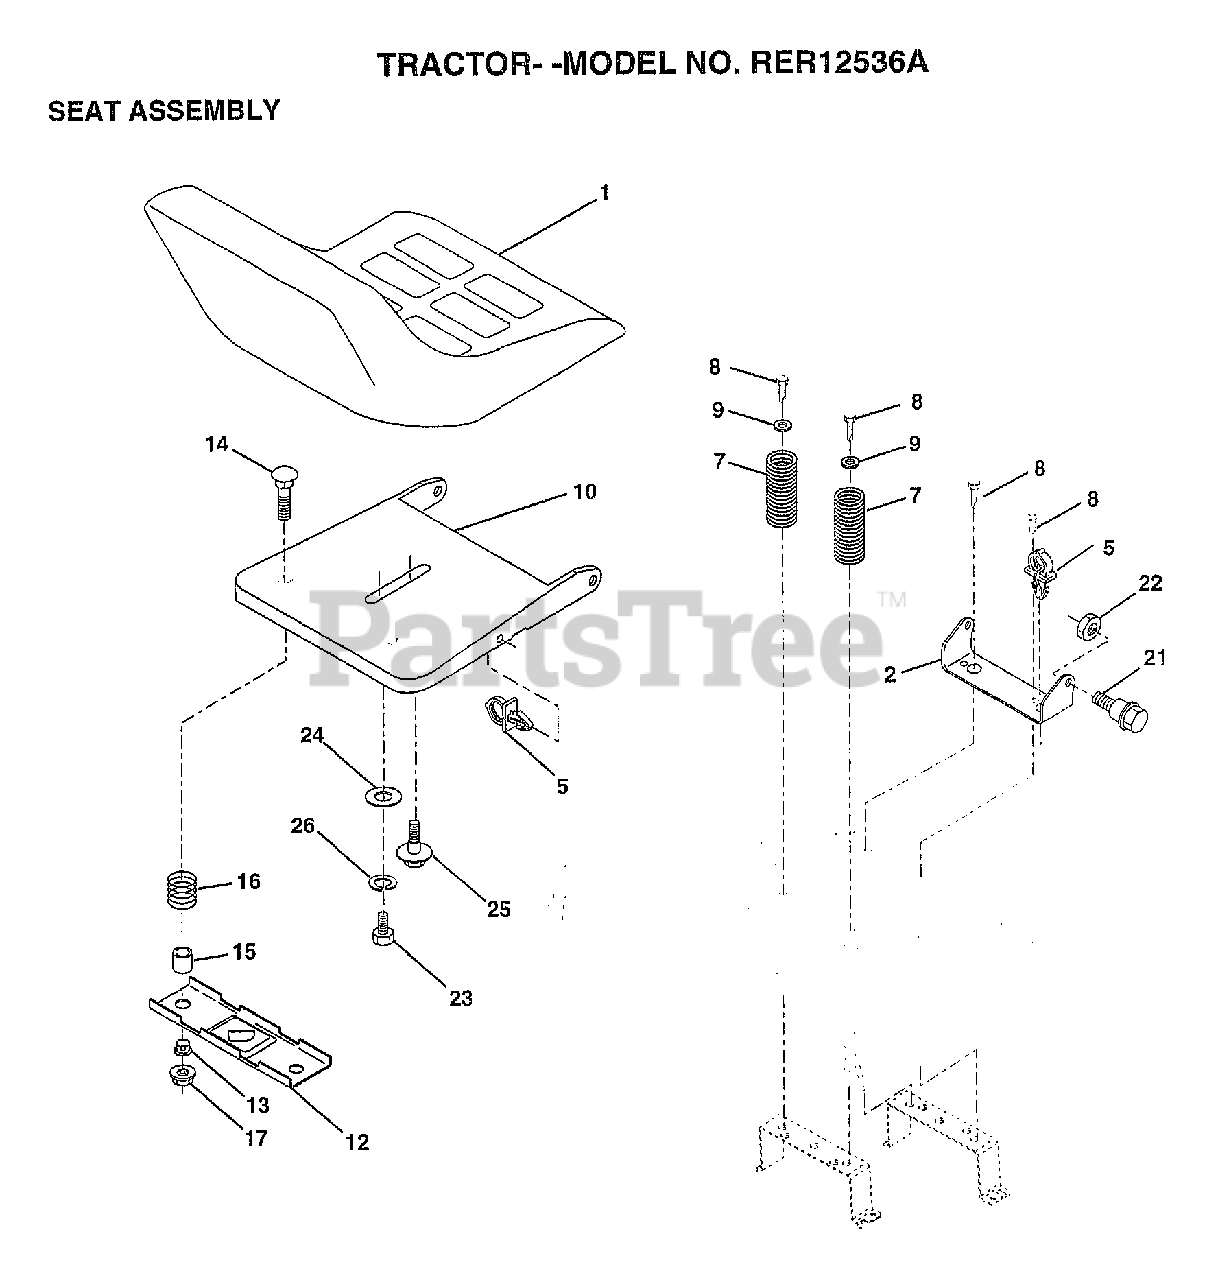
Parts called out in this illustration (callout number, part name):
2	BRACKET PVT SEAT
5	CLIP.PUSH-IN.HING
7	SPRING COMPRESSIO
8	SCREW GTV
9	WASHER
10	PAN-SEAT
12	BRKT SWITCH
13	BUSHING
14	BOLT-RD HD SQ NK
15	SPLIT SPACER
16	SPRING
21	"BOLT,SHOULDER"
22	NUT
23	BOLT
24	WASHER
25	"BOLT,SHOULDER"
26	LOCKWASHER
